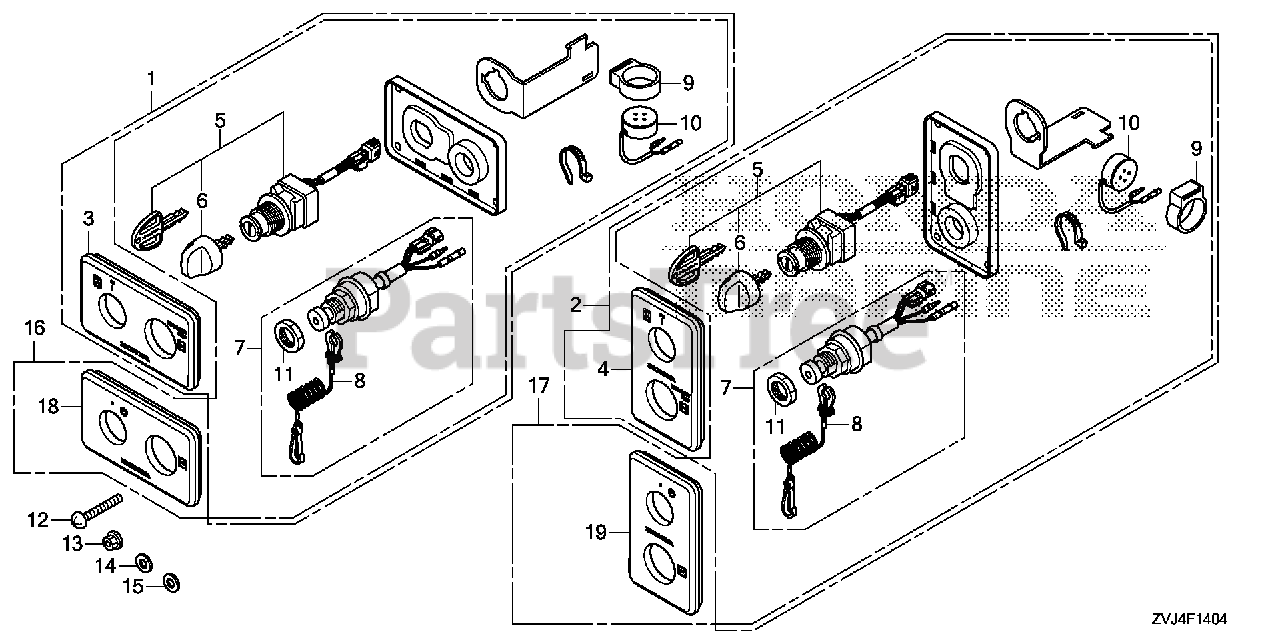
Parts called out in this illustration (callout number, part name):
1	PANEL ASSY., KEY SWITCH (SMART)
2	PANEL ASSY., KEY SWITCH (SMART)
3	PANEL, KEY SWITCH
4	PANEL, KEY SWITCH
5	SWITCH ASSY., COMBINATION (SMART)
7	SWITCH ASSY., EMERGENCY STOP
8	WIRE, EMERGENCY
9	SUSPENSION, AUDIBLE PILOT
10	BUZZER, WARNING
12	SCREW, PAN (5X40)
13	NUT, FLANGE (5MM)
14	WASHER, PLAIN (5MM)
15	WASHER, SPRING (5MM)
16	PANEL ASSY., KEY SWITCH (SMART)
17	PANEL ASSY., KEY SWITCH (SMART)
18	PANEL, KEY SWITCH
19	PANEL, KEY SWITCH
